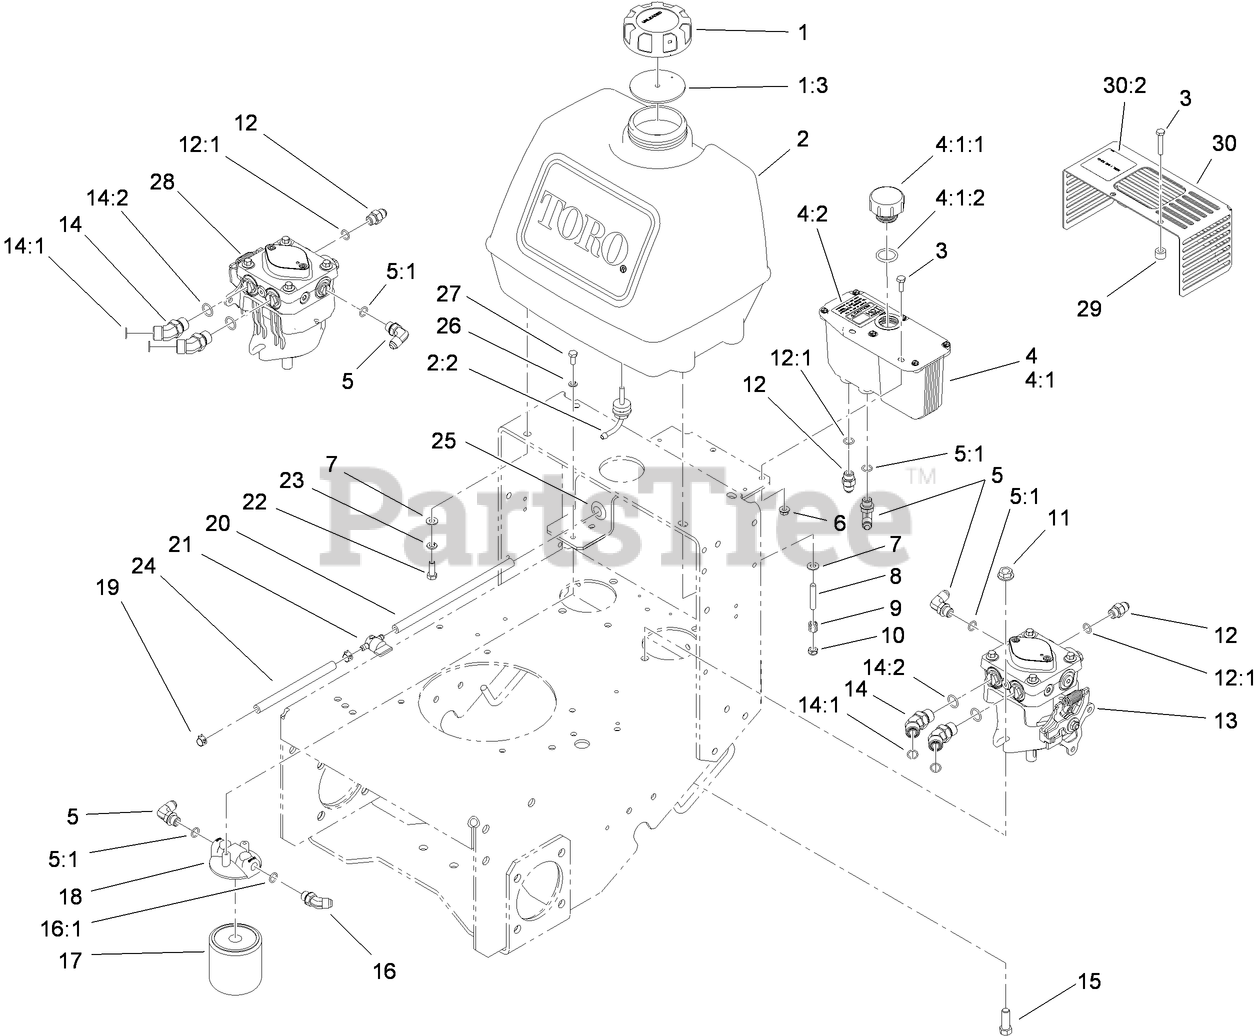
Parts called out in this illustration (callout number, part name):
1	GAS CAP ASM
1:3	GASKET-CAP, GAS
2	FUEL TANK ASM
2:2	FITTING-FUEL, BULKHEAD
3	SCREW-HH
4	HYD RESERVOIR ASM
4:1	Reservoir-HYD
4:1:1	CAP-RESERVOIR, HYD
4:1:2	GASKET-CAP
4:2	DECAL-WARNING
5	FITTING-ELBOW, 90 DEG
5:1	O-RING
6	NUT-HF
7	WASHER-PLAIN
8	STUD-THREADED
9	SPRING-TANK, FUEL
10	NUT-LOCK, NI
11	NUT-HF
12	FITTING-STRAIGHT
12:1	O-RING
13	HYD PUMP ASM
14	FITTING-HYD, 45 DEG
14:1	O-RING
14:2	O-RING
15	SCREW-HH
16	FITTING-ELBOW, 45 DEG
16:1	O-RING
17	FILTER-OIL, HYD
17	FILTER-OIL, HYD (WINTER)
18	HEAD-FILTER
19	CLAMP-HOSE
20	HOSE-FUEL
21	VALVE-FUEL
22	SCREW-HH
23	WASHER-LOCK
24	HOSE-FUEL
25	GROMMET
26	WASHER-LOCK
27	SCREW-HH
28	HYD PUMP ASM
29	Spacer
30	SHIELD ASM
30:2	DECAL-WARNING
